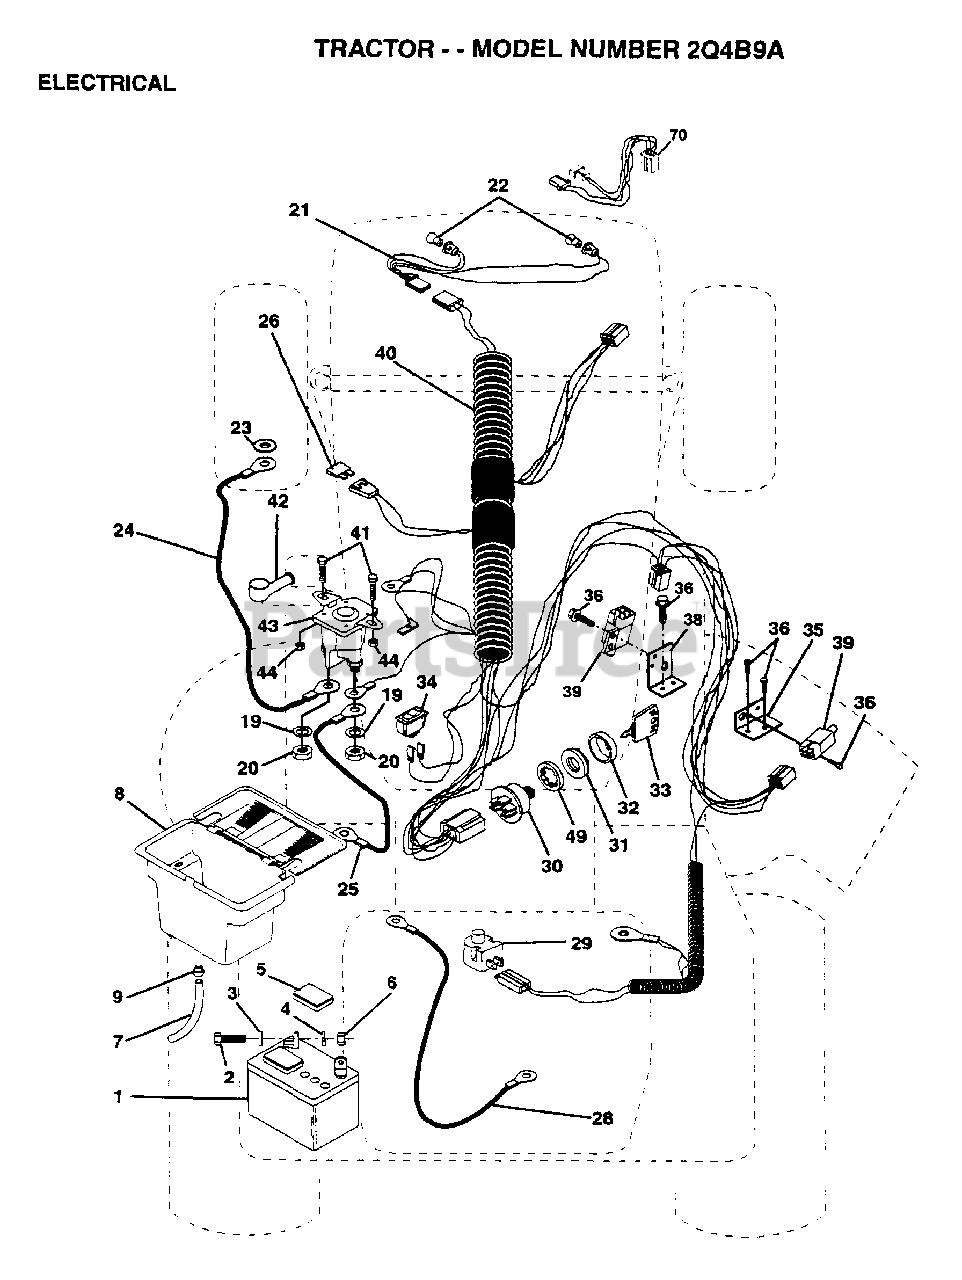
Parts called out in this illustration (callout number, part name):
2	BOLT LT
3	WASHER
4	LOCKWASHER
5	"CAP,BATTERY "
7	TUBE T
9	HOSE CLAMP T
20	NUT
21	"HARNESS,LIGHT SOC"
22	HEADLAMP BULB
23	LOCKWASHER
24	"CABLE T, BATTERY"
26	FUSE HYT
28	CABLE T
29	SWITCH SEAT
32	COVER KEY SWITCH
33	KEY MLD GEN DELTA
34	SWITCH LT
35	BRACKET LT
36	SCREW
38	BRACKET SWITCH IN
39	SWITCH INTERLOCKT
40	HARNESS IGN DASH
41	BOLT HXHD FIN
44	NUT HXKEP 1/4X20
49	LOCKWASHER
70	HARNESS.ENG.DUAL
